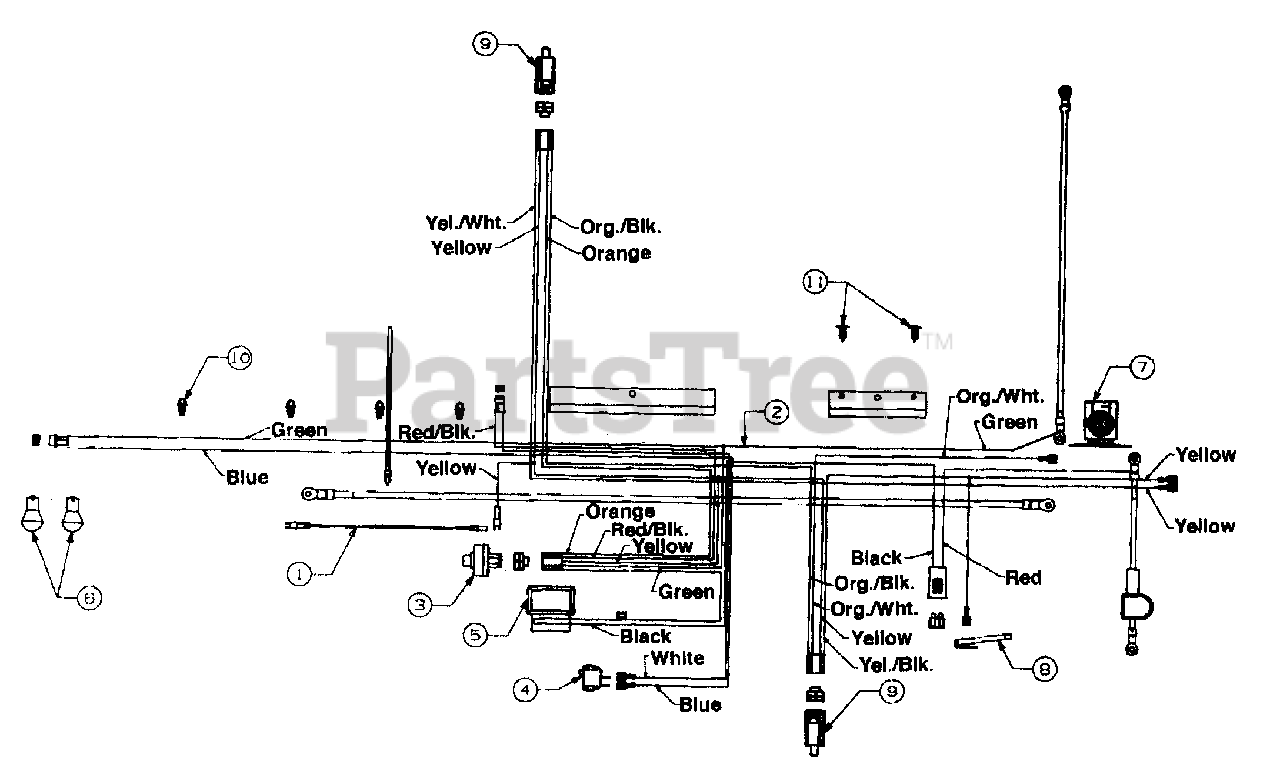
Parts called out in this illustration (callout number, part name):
1	Harness Adapter (Mag.)
2	Wire Harness w/ Light Switch and Amp
3	Ignition Switch
4	Light Switch
5	Ammeter
6	Bulb (Headlight)
7	Solenoid
8	Safety Switch (Reverse)
9	Safety Switch
10	Wire Retainer Clip
11	Ratchet
